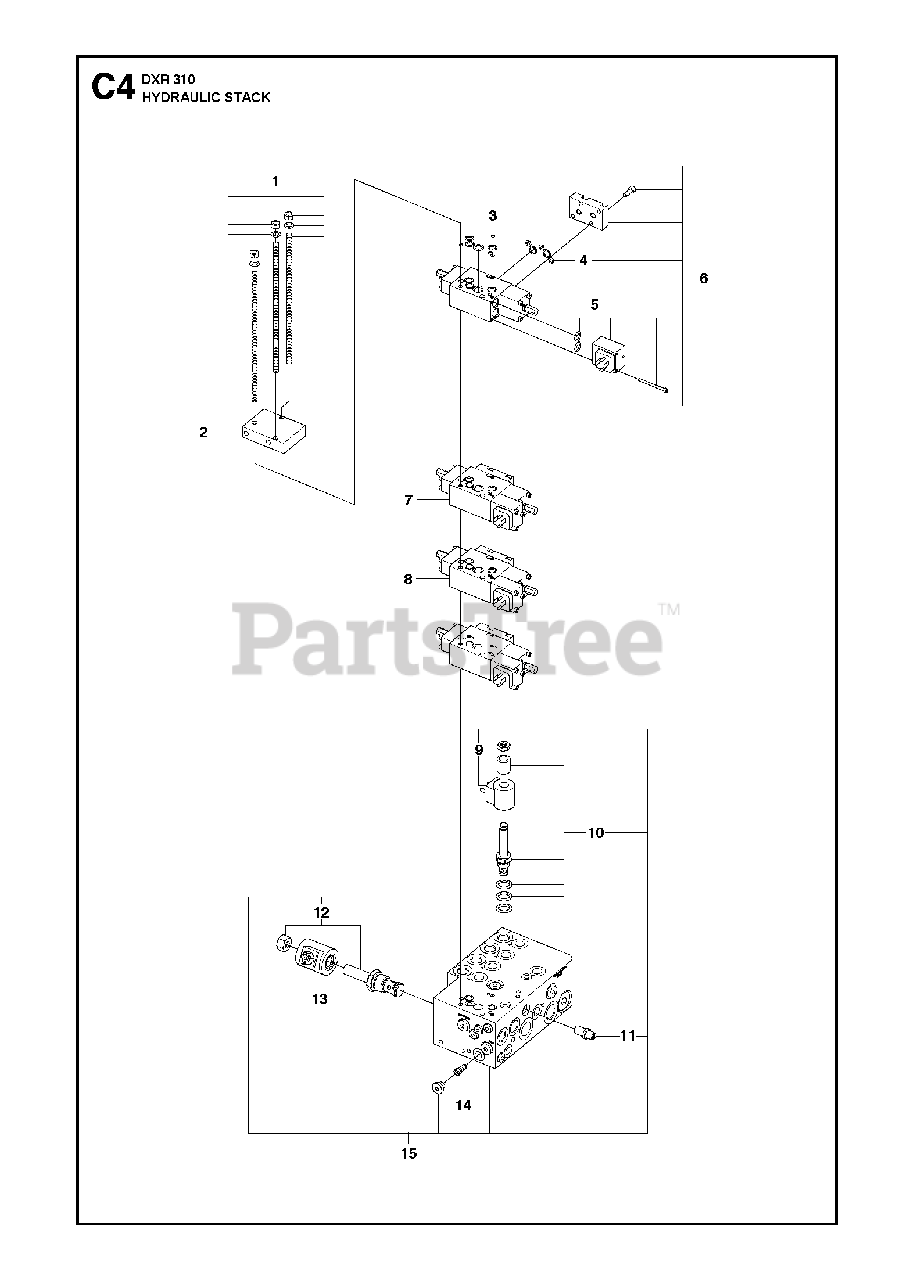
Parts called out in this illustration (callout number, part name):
8	VALVETrack drive motor left & right
11	VALVEPressure reducing valve, Pilot pressure
12	VALVEcirculation valve
14	VALVEShuttel valve, Load-sensing signal
